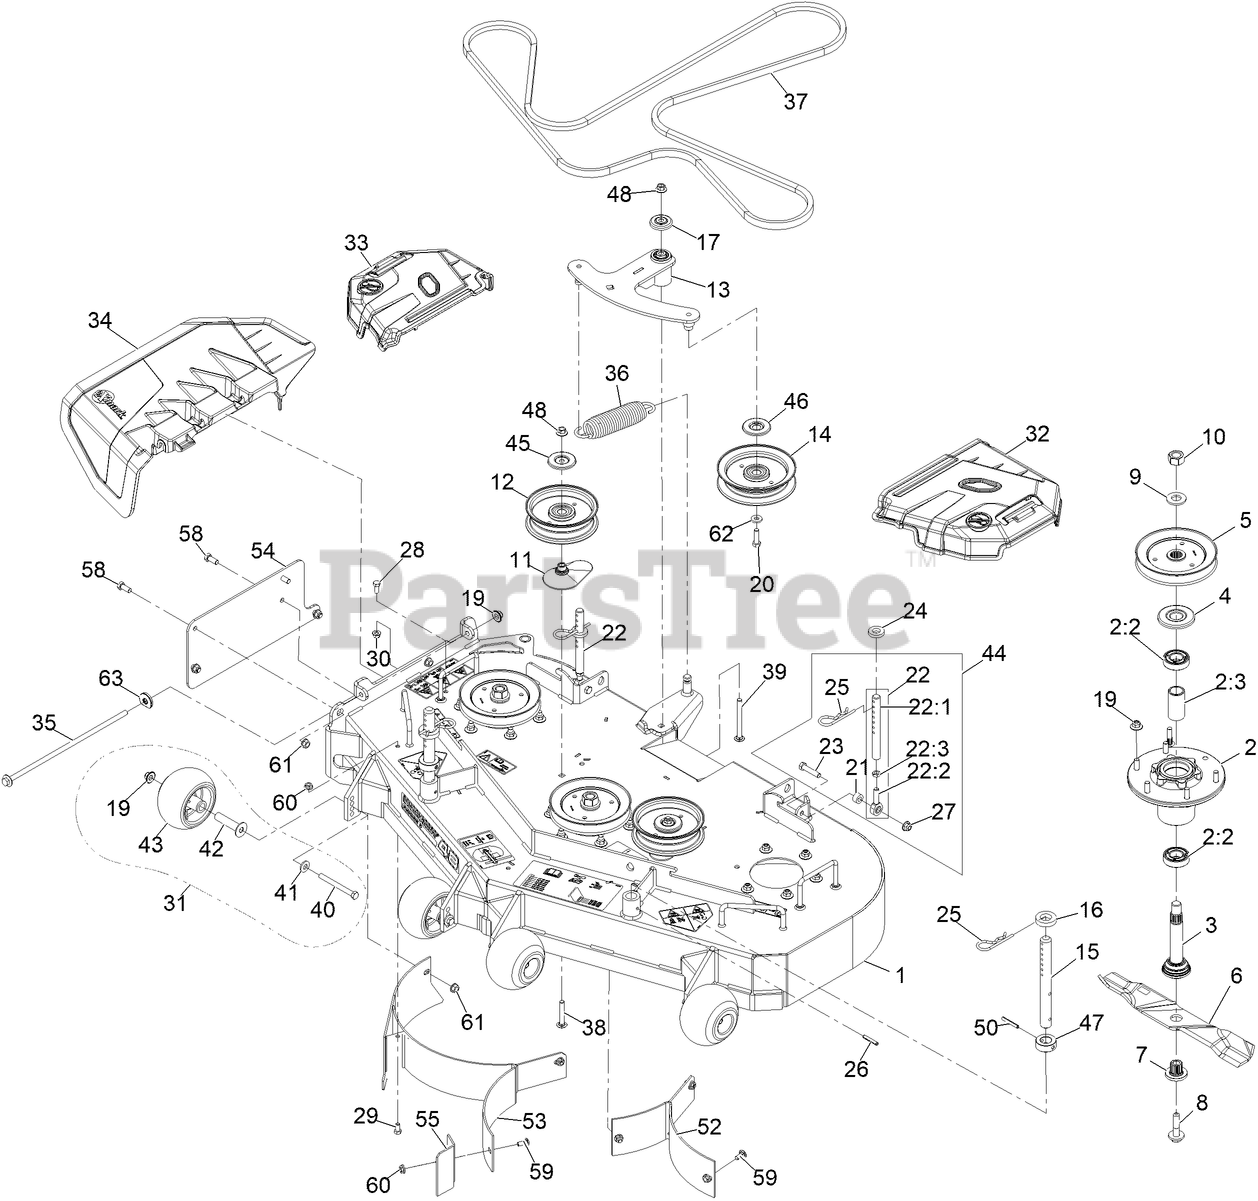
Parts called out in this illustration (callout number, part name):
1	ASM-Deck 48" W/Decals
2	ASM-CUTTER HSG WITH BEARINGS
2:2	BEARING-BALL
2:3	SPACER-BEARING
3	ASM-SPINDLE AND SEAL
4	GUARD,BEARING TOP .989
5	Sheave,Blade Drive 5.90
7	BUSHING,SPLINED
8	SCREW,SEMS 1/2-20 X 2.19
10	NUT-HEX
11	SPACER-PULLEY
12	IDLER-PULLEY, FLAT 5.00X1.31
13	ASM, DECK IDLER
14	IDLER-PULLEY, FLAT
15	ROD, DECK SUPPORT TTS
16	SPACER-DECK SUPPORT
17	GUARD-TOP
19	Nut-Nyloc 3/8-16 Flg
20	SCREW-HH
22:1	LINK,SUPPORT
22:2	BALLJOINT
22:3	NUT-HJ
23	SCREW-HH
25	PIN,HAIR COTTER
27	NUT-HF, NI
28	SCREW-HH
29	SCREW-HH
30	NUT-HF, NI
31	KIT, ANTI-SCALP ROLLER
32	SHIELD, LT
33	SHIELD, RT
34	Chute-Deck Discharge
35	Pin, Chute
36	SPRING-EXTENSION
38	BOLT-CARR, SHORT NECK
39	SCREW-CARR
40	SCREW-HH 3/8-16 X 3 3/4 GR 8
41	WASHER-BELLEVILLE
42	AXLE, ROLLER
43	ROLLER-SCALP, ANTI
44	KIT,SUPPORT LINK W/PIN
45	SHIELD-DUST
46	SHIELD-GUARD, DUST
47	COLLAR, DECK HEIGHT PIN
50	PIN-ROLL
53	BAFFLE-RH
54	PLATE, MULCH COVER
55	BAFFLE-BLOCKER
58	SCREW-HH
59	BOLT-CARR
61	NUT-HHF, WHIZ
63	Retainer, Chute
